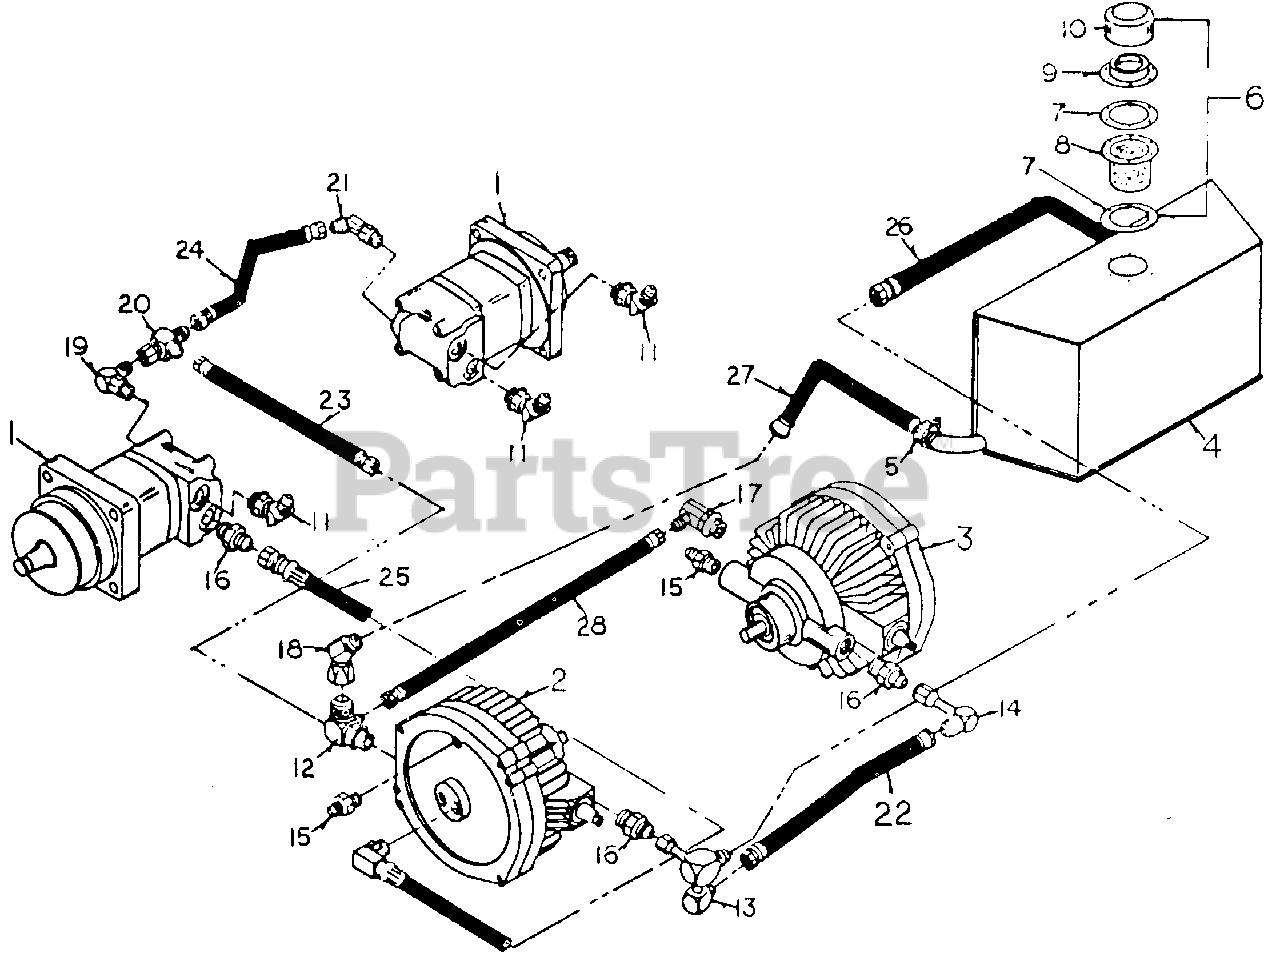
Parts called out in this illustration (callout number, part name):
3	Pump, RH
4	Hydraulic Oil Tank
5	Hose Clamp
6	Hydraulic Fill Cap Assembly
8	Strainer
9	Fill Neck
11	Male Tube, 45ø Male O-ring Adapter
13	Special Adapter
14	Male Tube, 90ø Female Swivel Adapter
15	Male Tube, Male O-ring Adapter
16	Male Tube, Male O-ring Adapter
17	Male Tube, 90ø Male O-ring Adapter
18	Male Tube, 45ø Female Swivel Adapter
19	Male Tube, 90ø Male O-ring Adapter
20	Male Tube, Female Swivel Tee
21	Male Tube, 45ø Female Swivel Adapter
22	Hose, 1/2" lD x 18" Long, Easy Couple
23	Hose, 1/4" ID x 14" Long, Easy Couple
24	Hose, 1/4" ID x 20" Long, Easy Couple
25	Hose, 1/2" ID x 36 1/2" Long
26	Hose, 3/4" ID x 22" Long, Easy Couple
27	Hose, 3/4" ID x 18" Long, Easy Couple
28	Hose, 1/2" ID x 20" Long, Easy Couple
